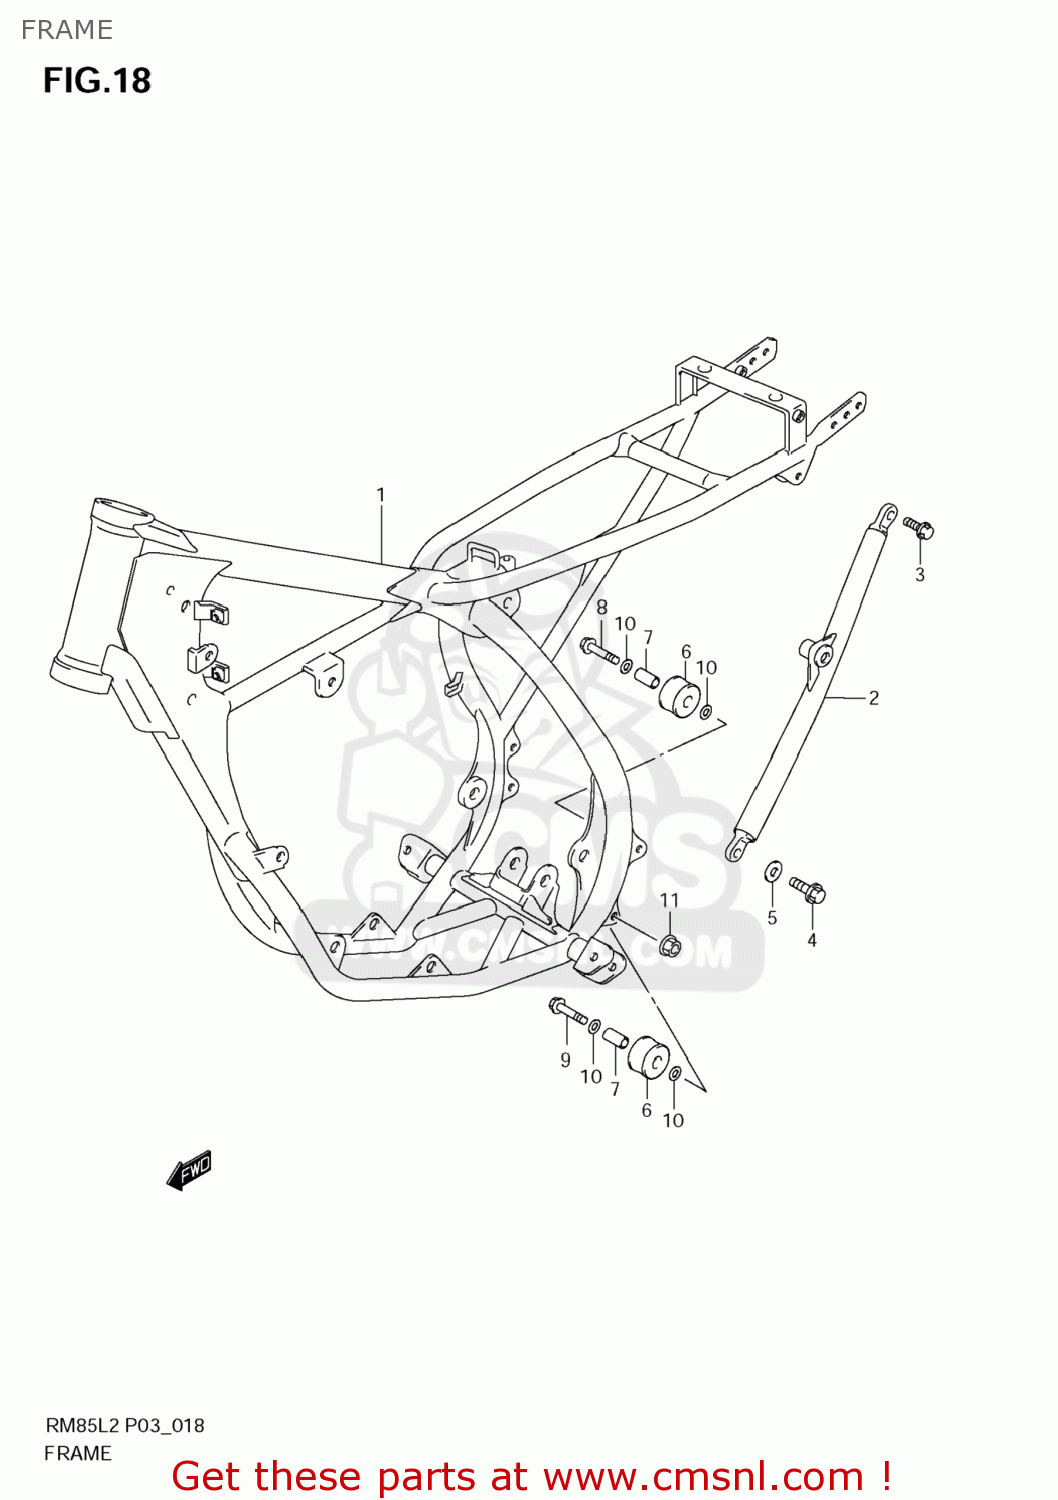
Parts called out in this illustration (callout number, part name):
1	FRAME(GRAY)
2	TUBE,FRAME SIDE,L(GRAY)
3	BOLT(8X22)
4	BOLT(8X16)
5	WASHER(8.5X18X2)
6	ROLLER,CHAIN CONTROL
7	SPACER(8.6X12.2X25.5)
8	BOLT(8X38)
9	BOLT(8X55)
10	SHIM(8X16X1)
11	NUT
